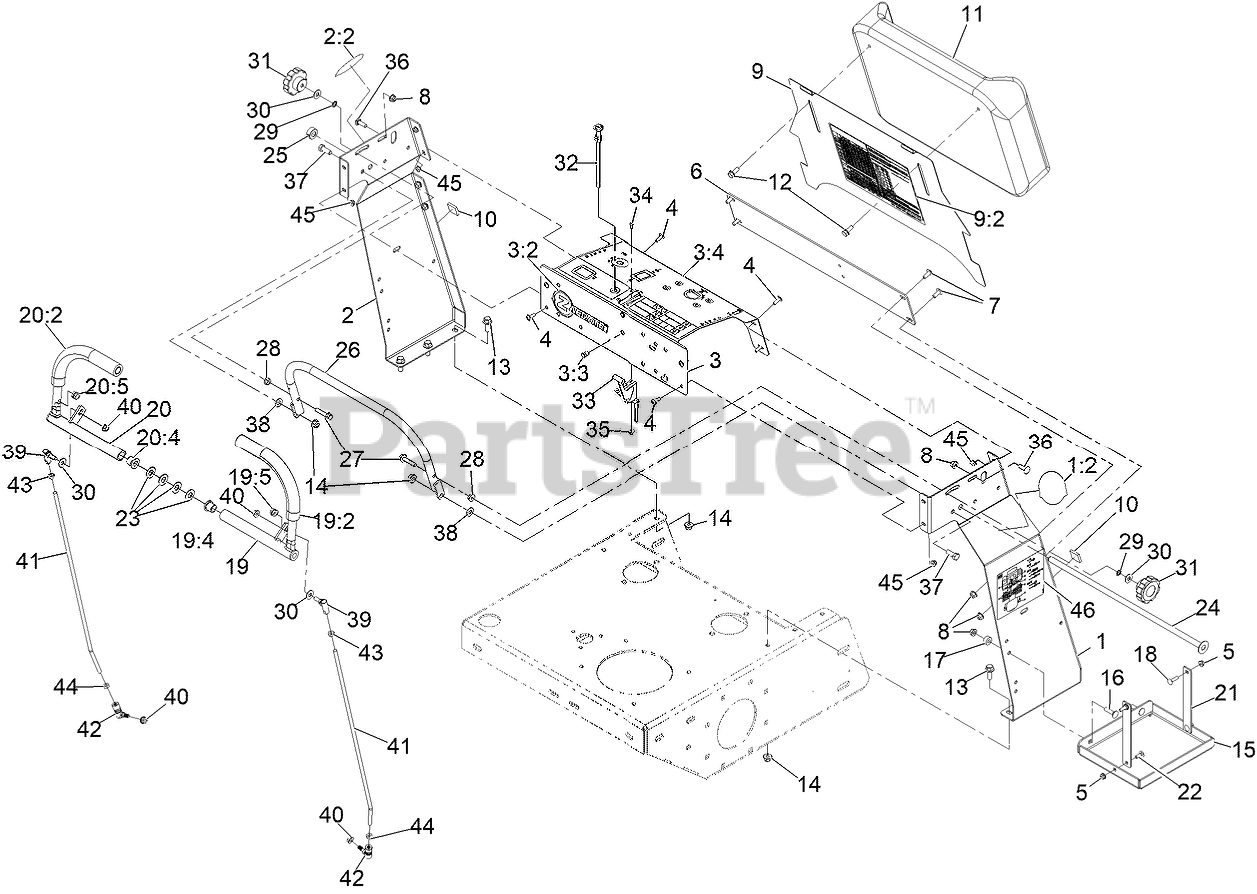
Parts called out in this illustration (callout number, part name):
1	PANEL-TOWER, LH
1:2	Decal-Z-Logo
2	PANEL-TOWER, RH
2:2	Decal-Z-Logo
3	PANEL-CONTROL
3:2	DECAL-Z-AERATE LOGO
3:3	Nut-Clinch, Hex
3:4	Decal-Control Panel
4	Screw-Hsbhf
6	PLATE-FACE
7	SCREW-PTH
8	NUT-HF, NI
9	PLATE-PAD,KNEE
9:2	Decal-Spray Chart
11	PAD-KNEE, Z-LOGO
12	SCREW-HHF
13	SCREW-HHF 3/8-16 X 1
14	NUT-HF, NI
15	TRAY-BATTERY
16	Bolt-Carriage 5/16-18 X 1 1/4
18	SCREW-CARR
19	HANDLE-CONTROL, LH ASM
19:2	GRIP-CONTROL, MOTION
19:4	Bushing,Flange,0.50 ID,0.75 OD
19:5	Grommet-Rubber
20	HANDLE-CONTROL, RH ASM
20:2	GRIP-CONTROL, MOTION
20:4	Bushing,Flange,0.50 ID,0.75 OD
20:5	Grommet-Rubber
21	Strap-Battery
22	BOLT-CARR
23	WASHER-PIVOT
24	Rod-Pivot, Joy Stick
26	Bar-Speed [red]
27	SCREW-HHF
28	Nut-Flange
29	Washer-Lock
30	FLAT WASHER, 5/16 NOM,ST
31	KNOB-FLUTED
32	CABLE-CHOKE
33	CABLE-THROTTLE
34	Screw-HSBH
35	Nut-Hex Flange
36	SCREW-CARR
37	SCREW-HH
38	WASHER-FLAT
39	Balljoint-SS
40	Nut-HHF
41	ROD-CONTROL
42	Ball Joint-Quick Disconnect, SS
43	Nut-Hex
44	Nut-Hex
45	Nut-Hex Flange
46	Decal-Service Aid
